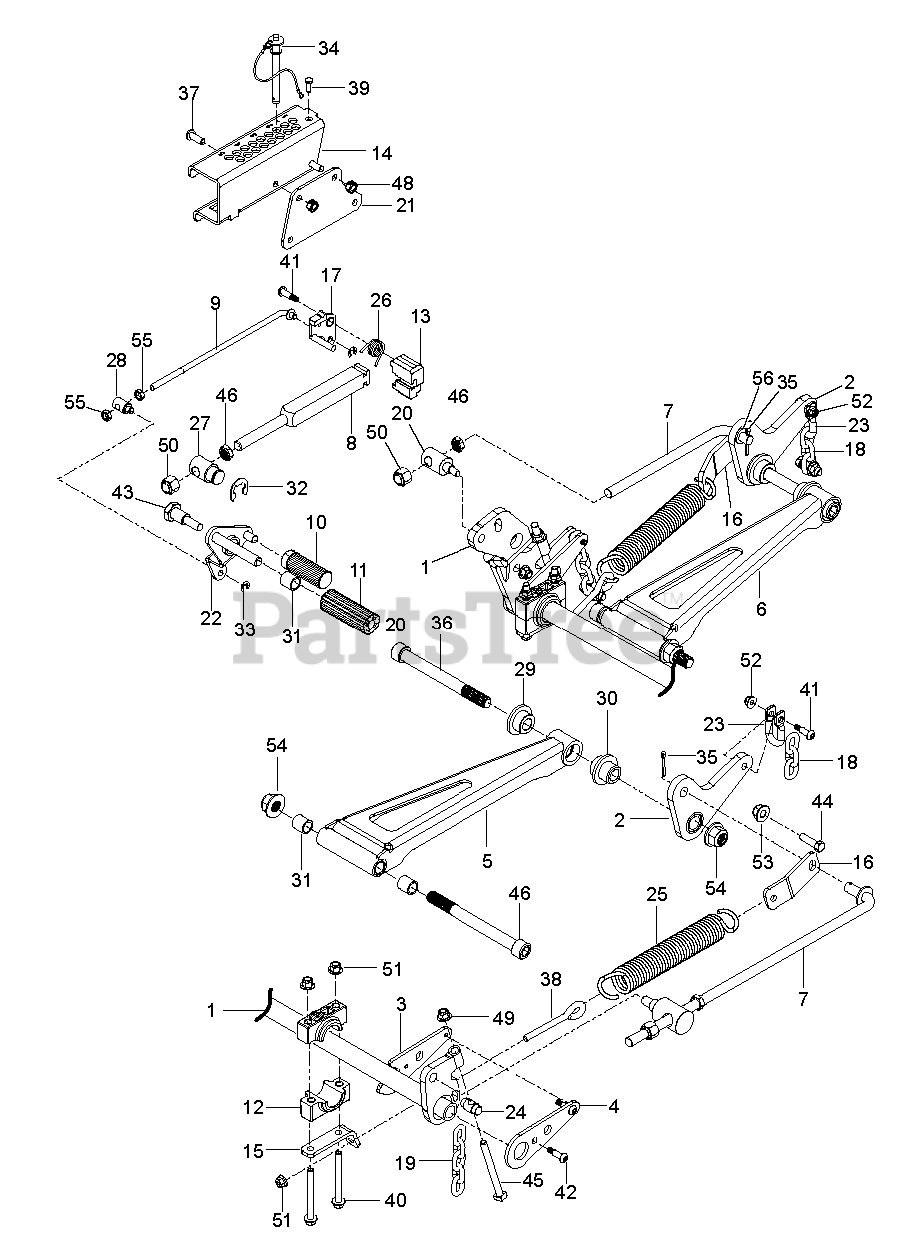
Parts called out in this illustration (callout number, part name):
1	SHAFT.WLDMNT.FRNT.DECK.LFT.PNT
2	KIT.ARM.BELLCRANK/BUSHINGS.RT
2	KIT.ARM.BELLCRANK/BUSHINGS.LT
3	ARM.DECK.LIFT.INNER.BLACK
4	ARM.LIFT.DECK.OUTER.POWER.BLK
5	ARM.DRAWBAR.LH
6	ARM.DRAWBAR.RH
7	ROD. CONNECTING
8	ROD.HEIGHT.GAUGE
9	ROD.RELEASE.CONNECTING.TOE
10	PEDAL, DECK HEIGHT
11	PAD, FOOT PEDAL
12	BLOCK, PILLOW
13	BLOCK.ROD.END
14	BRACKET.ADJUSTMENT.HEIGHT.ORNG
15	BRACKET.PILLOW.BLOCK.PNT.BLACK
16	BRACKET SPRING BLACK (X428)
17	KIT.LEVER.LOCK.W/BUSHING
18	LIFT CHAIN - 3 LINK
19	LIFT CHAIN
20	PIVOT.CONNECTING.ROD
21	PLATE.HEIGHT.GAUGE.MOUNT.PNT
22	LEVER ASSY TOE RELEASE
23	SHACKLE.CHAIN
24	SHAFT.TRUNNION.ATTACH
25	SPRING EXTENSION, DECK LIFT, H
26	SPRING.TORSION.RELEASE.LEVER
27	SWIVEL.HEIGHT.BAR
28	SWIVEL.TOP.RELEASE
29	BUSHING.DECK.INNER
30	BUSHING.DECK.OUTER
31	BUSHING, SLEEVE 3/4 X 1.0
32	E-RING 1"
33	E RING 3/8"
34	PIN.PUSH.BUTTON.DETENT..5X3.5
35	COTTER PIN 1/8 X 2
36	SCREW.SOCKET.HEADCP.3/4-10X7.5
37	SCREW.BUTTON.HEAD.CAP.3/8-16X1
38	EYE BOLT, 3/8 X 4"
39	SCR 5/16-18 X 1/2 SELFTAP ZN
40	SCREW.HHFS3/8-16X3.75.GR8
41	SCREW.SHOULDER.375X875.5/16-18
42	SCREW.SHLDR..375.5/16-18.88.LG
43	BOLT, SHOULDER
44	HCS 7/16C X 1 1/2
45	SCREW.HHC.7/16-14 X 4.50
46	NUT.HH.THIN.NYL.5/8-11 GR5
48	NUT 3/8C CENTERBLOCK
49	NUT FLANGE, NYL 7/16-14
50	NUT 5/8-11 NYLOC
51	NUT 3/8-16 HEX FLG NYLOC ZD
52	5/16-18 NYLOC FLANGE NUT
53	NUT 7/16-14 HEX WHIZ LK
54	NUT.HEX.FLANGED.3/4-10.NYLOK
55	NUT 3/8-24 JAM
